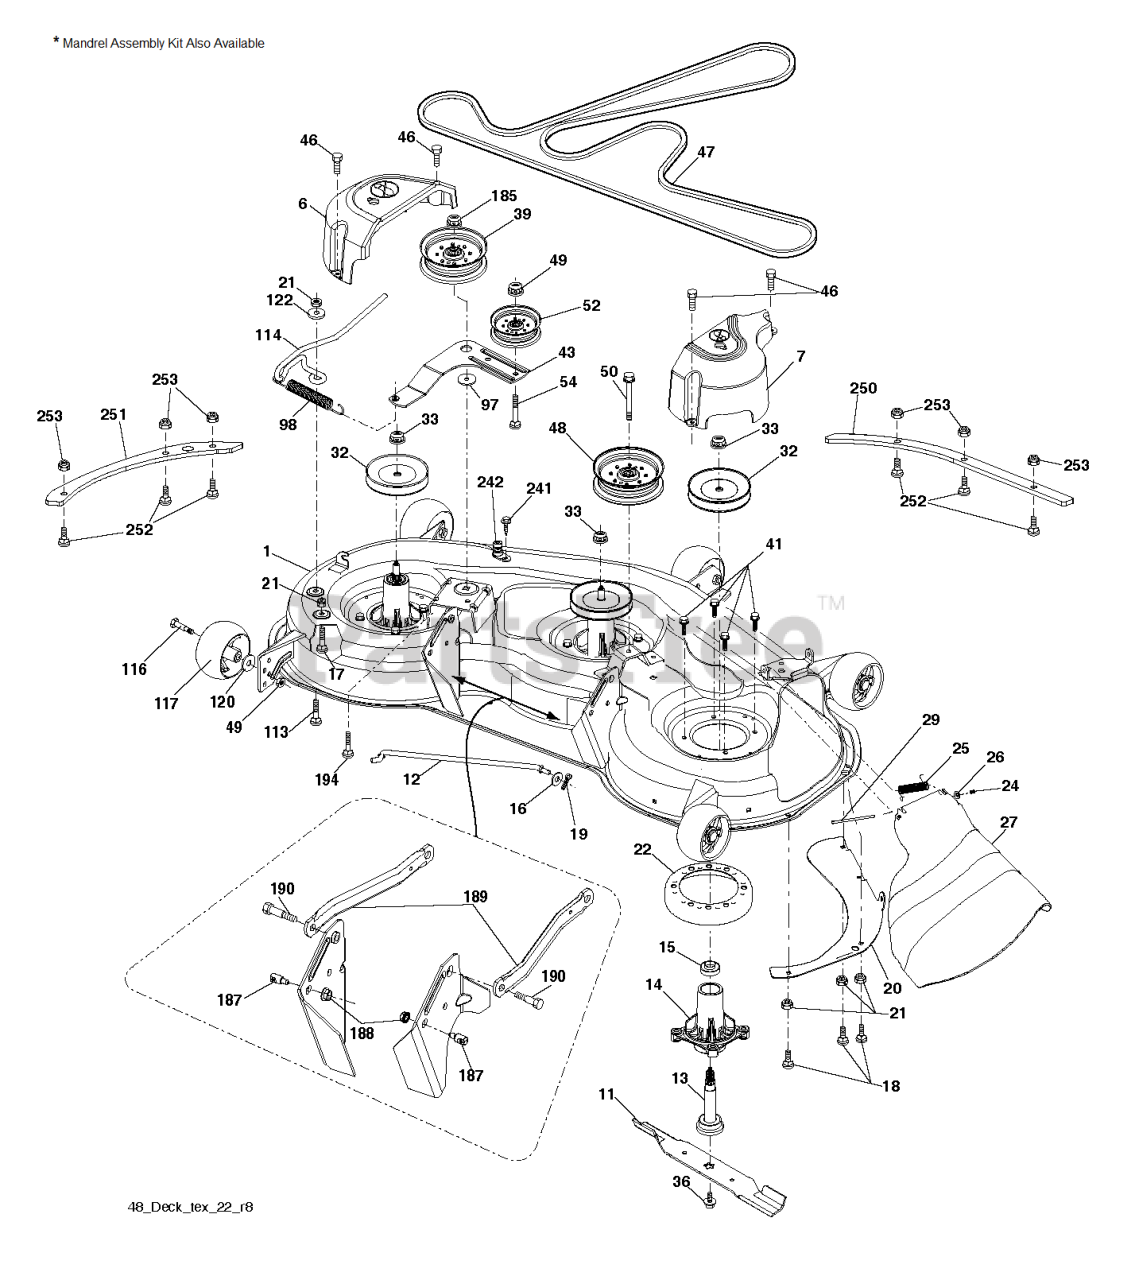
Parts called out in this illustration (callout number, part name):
1	DECK.SVC.48"
6	COVER.MANDREL.LH.48"(2 2)
7	COVER.RH.MANDREL
11	48" HI-LIFT BLADE
12	ROD.ANTI.SWAY.48/54"K4
13	SHAFT ASSY, MANDREL SHAFT
14	HOUSING.MANDREL.4PT.
15	BEARING.MANDREL.TOP.EXTENDED
16	WASHER
17	BOLT
18	BOLT
19	PIN.COTTER.5/16.BOW TI
20	BAFFLE, VORTEX MWR
21	LOCKNUT
22	STRIPPER.MANDREL.ROUND.BLACK
24	CAP-SLEEVE LT
25	SPRING, TORSION
26	NUT PUSH M
27	DEFLECTOR SUBS TO 532 180655
29	ROD.HINGE
32	PULLEY MANDREL
33	NUT.FLANGE.LOCK.TOP
36	SCREW.SEMS.7/16-20X1.HEX.HEAD
39	RB PULLEY.IDLER.4.50/HUB SPEC
41	BOLT.HEX.WASHR.HED.313-18X1.19
46	SCREW.1/4-20X5/8
47	BELT.DRIVE.DECK
48	PULLEY.IDLER.2006
49	NUT LOCK FLG 3/8-16 UNC
50	SCREW TT 3/8-16X2-1/4 UNC
52	PULLEY.IDLER.48"PRIMARY
54	BOLT.3/8-16X1.50
98	SPRING, DECK DRIVE
113	RHSSNB 5/16C X 1.0
114	ROD.TENSION.RELIEF.TEX (2 2)
116	BOLT.SHOULDER.3/8-16X3-5/8.
117	Gage Wheel, Rally
120	WASHER
122	BUSHING.RELIEF.TENSION
185	NUT.LOCK.FLANGE.7/16
187	STUD.FASTNER.W/ANTI-ROTATE
188	NUT LOCK HEX FLANGE 5/16-18
189	ARM.SUSPENSION.MOWER
190	BOLT.SHOULDER
194	BOLT.HEX.WASHER.HEAD.7/16-24X
241	SCREW.TT.#10-32X.5.3/8.FLANGE
242	PORT.WASHOUT
250	PLATE.REIN.FRNT.BOLTON.48X431
251	PLATE.REIN.SIDE.BOLT.ON.48X431
252	RHSNB, 1/4-20 X 1, GR5
253	NUT T
280	MANDREL.W/SPCR.BRG.TALL.NONREV
